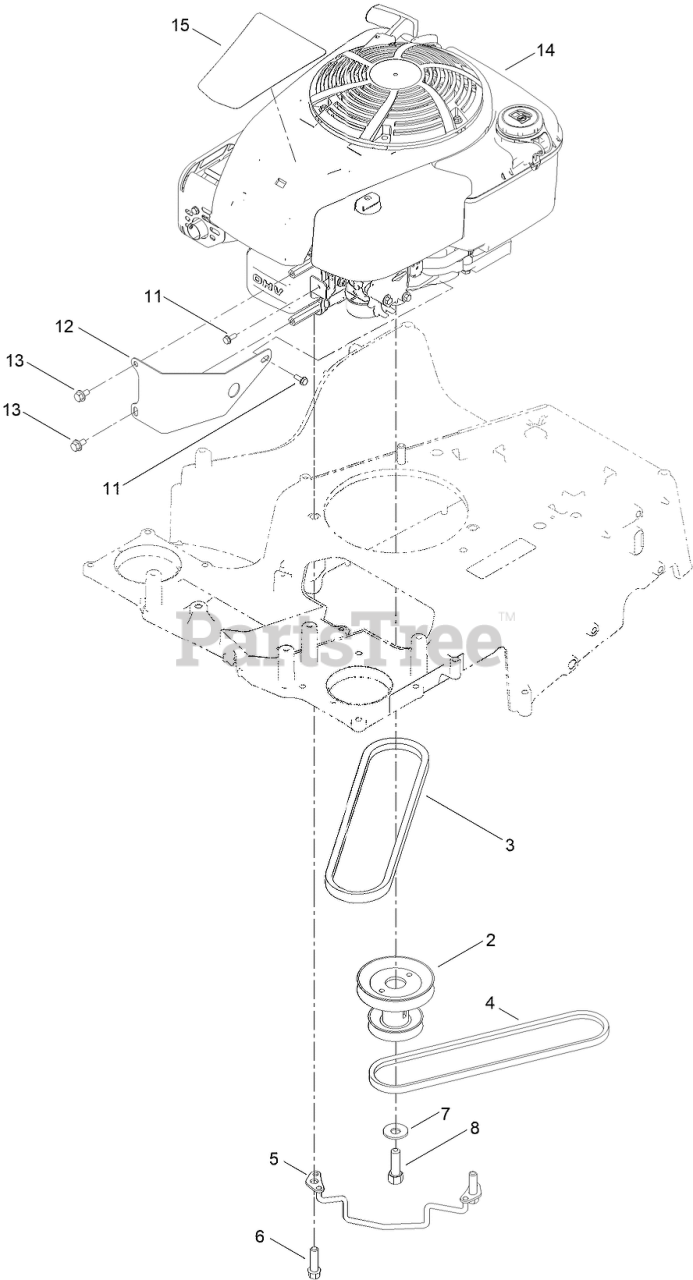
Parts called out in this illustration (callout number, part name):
2	PULLEY-ENGINE
3	V-BELT
4	V-BELT, TRACTION
5	GUIDE-BELT, WA
6	SCREW-TAPTITE
7	WASHER-BELLEVILLE
8	SCREW-HH
11	SCREW-TAPTITE
12	GUARD-ENGINE
13	SCREW-HHF
15	DECAL-SHROUD
